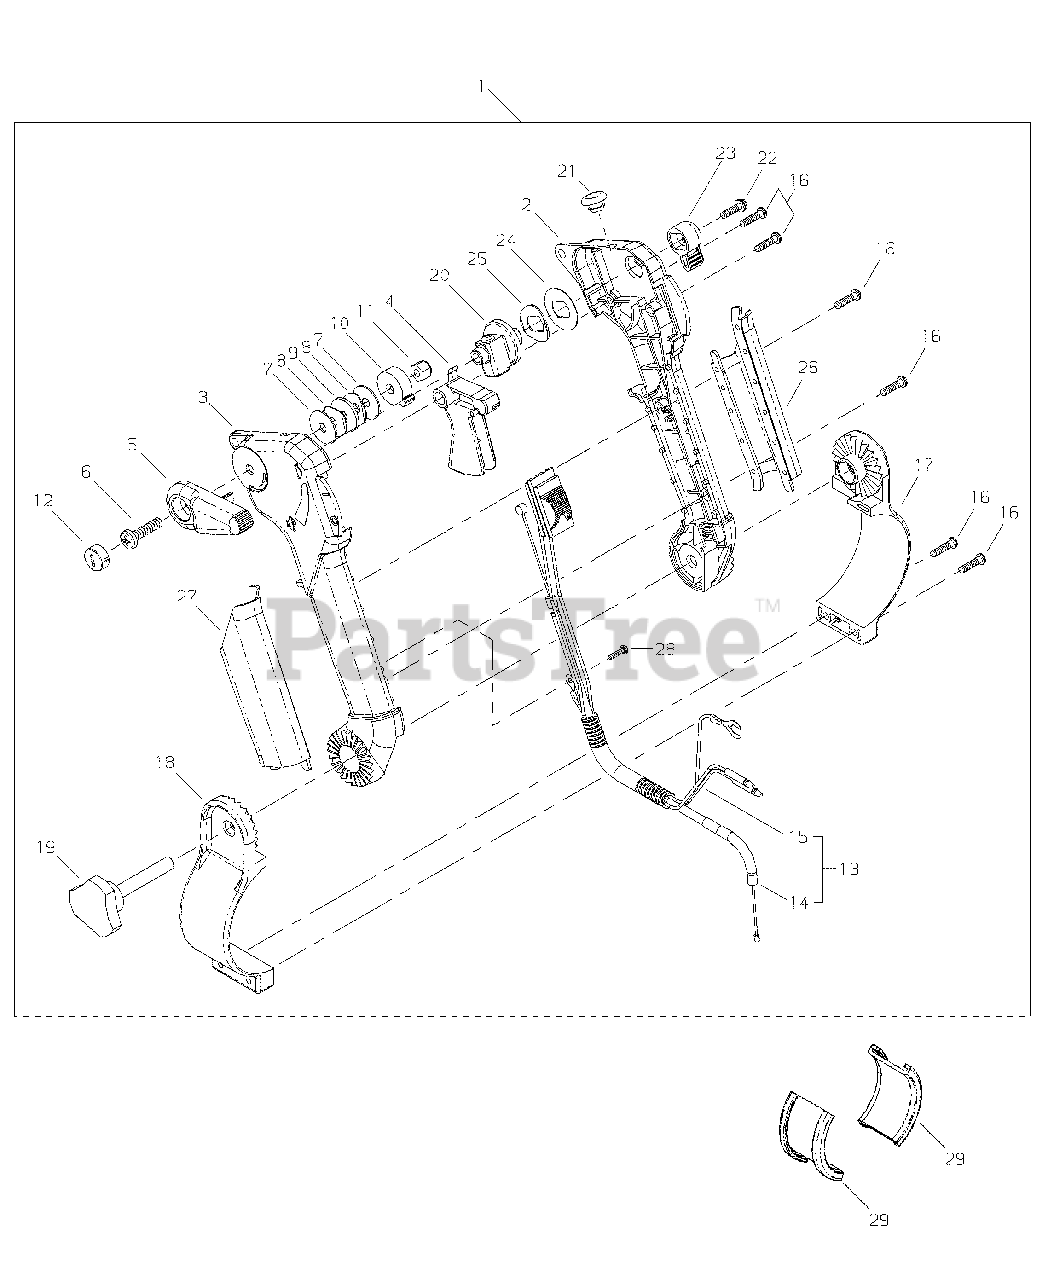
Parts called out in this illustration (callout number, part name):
1	THROTTLE CONTROL ASSY
2	CONTROL HANDLE - RIGHT
3	CONTROL HANDLE - LEFT
4	TRIGGER, THROTTLE
5	CONTROL, THROTTLE
6	BOLT M6×25
7	WASHER M6
8	WASHER, SPRING
9	WASHER M6
10	LEVER, THROTTLE
11	NUT, NYLON M6
12	CAP, BOLT
13	CABLE ASSY, CONTROL
14	CABLE, THROTTLE
15	SWITCH, ON-OFF
16	SCREW M4×16
17	BRACKET, RIGHT
18	BRACKET, LEFT
19	KNOB, SCREW
20	LIMITER ASSY, THROTTLE
21	PLUG, THROTTLE LIMITER
22	SCREW M4×16
23	LEVER, THROTTLE LIMITER
24	WASHER
25	WASHER, WAVE
26	GRIP, RIGHT
27	GRIP, LEFT
28	SCREW M3×8
29	SPACER
